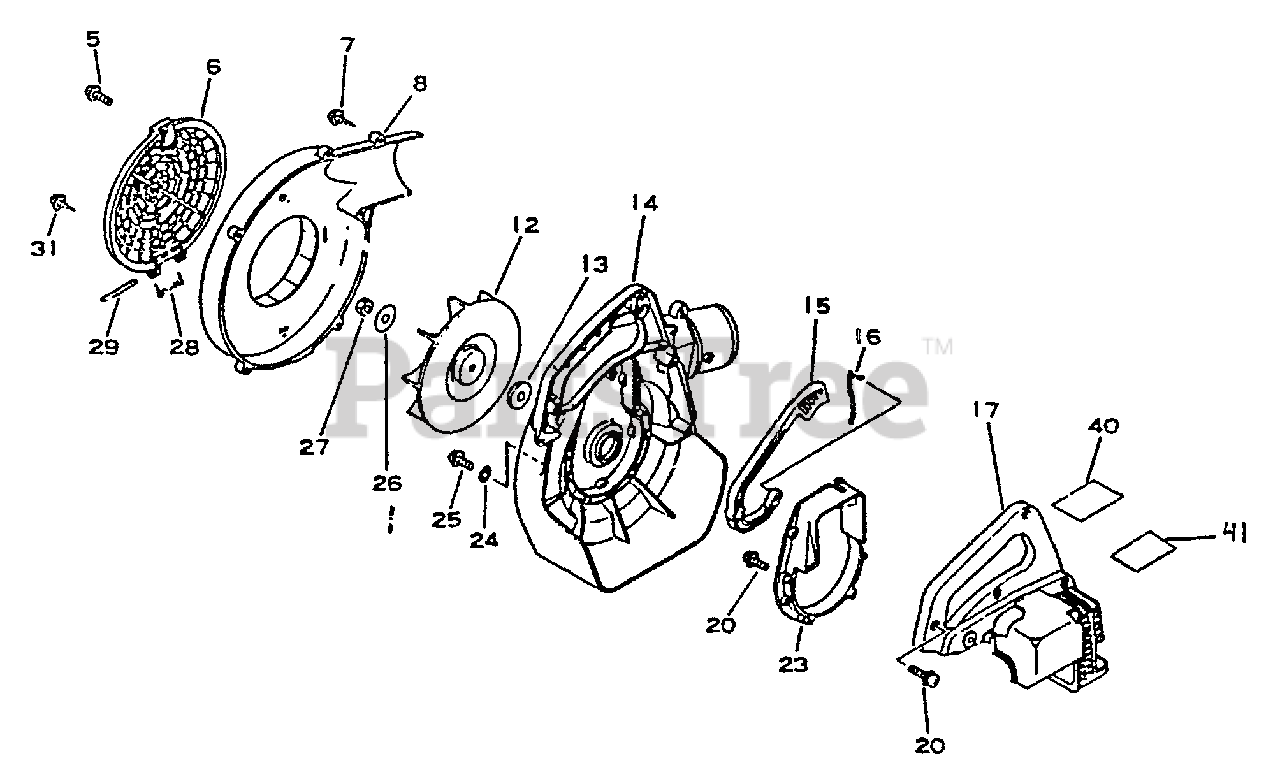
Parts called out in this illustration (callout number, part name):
5	SCREW 5×18
6	SHIELD, DEBRIS
7	SCREW 5×20
8	COVER, FAN - LEFT
12	FAN
14	COVER, FAN - RIGHT
15	TRIGGER, THROTTLE
16	ROD, THROTTLE
17	COVER, ENGINE
20	SCREW 4×18
23	BRACKET, ENGINE
25	SCREW 4×22
28	SPRING, COIL
29	PIN, INTAKE COVER
31	SCREW 5×20
40	LABEL - MODEL
41	LABEL, CAUTION
